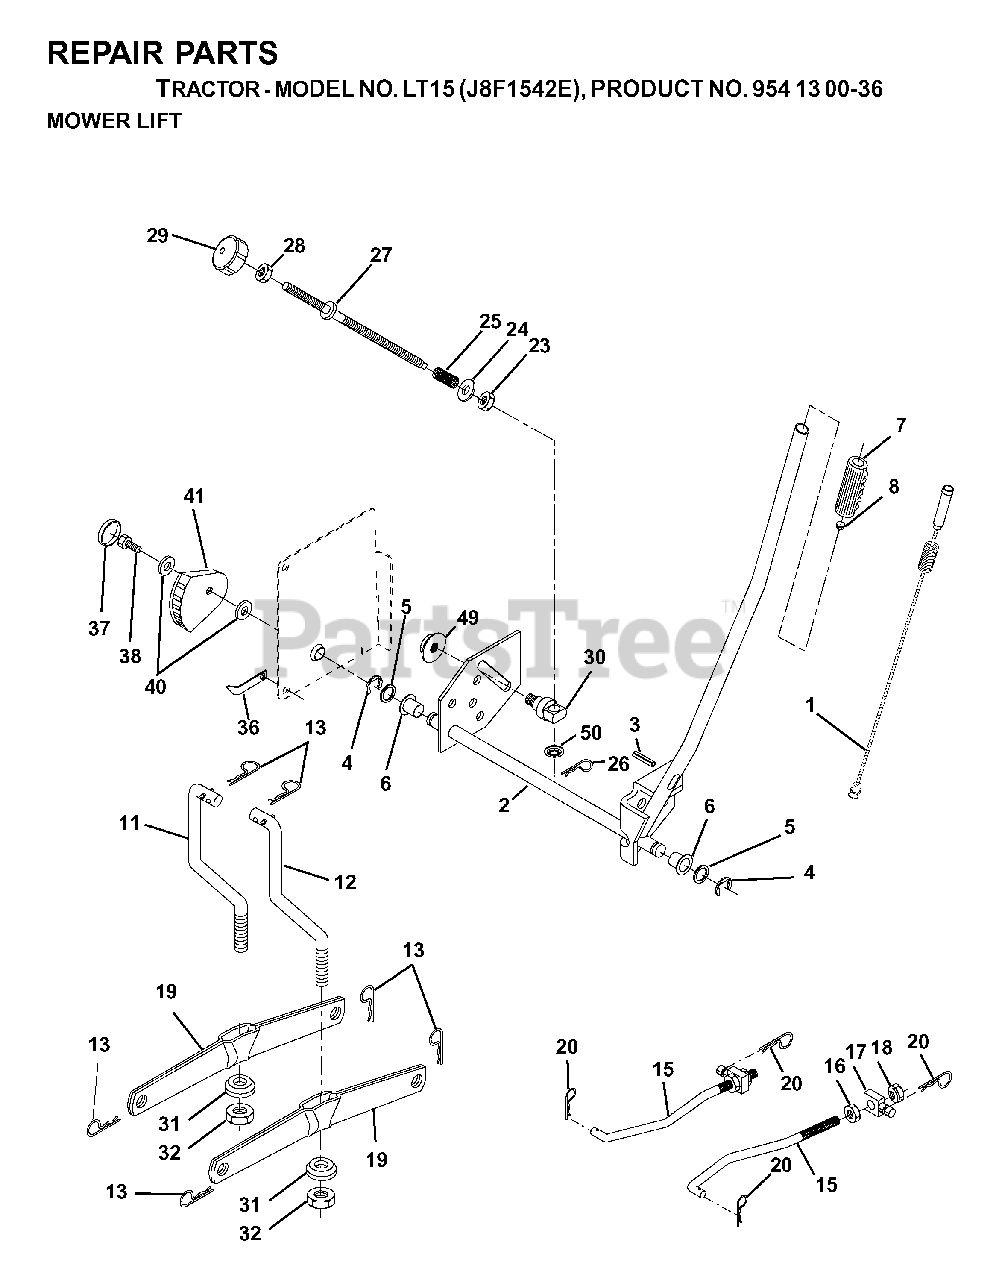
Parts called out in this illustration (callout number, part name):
1	WIRE ASM INNER W/ PLUNGER LT
2	SHAFT ASM R HANDLE
3	PIN GROOVE
4	RETAINING RING LT
6	BEARING.NYLON
7	GRIP HANDLE
11	LINK LIFT LH
12	LINK LIFT RH
13	RETAINER-SPRNG RB
15	LINK FRONT
16	NUT
17	TRUNION
18	NUT
19	ARM.REAR.SUSPENSION
20	SPRING RETAINER
25	SPRING**
26	RETAINER CLIP
27	ROD ADJ LIFT
28	NUT
29	KNOB INF 3/8-16
31	BEARING PIVOT
32	NUT CROWNLOCK 3/8-24
36	POINTER, HEIGHT INDICATOR
37	PLUG,HOLE
38	SCREW 5/16-18X1
41	IND. HEIGHT STLT
49	NUT
50	NUT PUSH M
